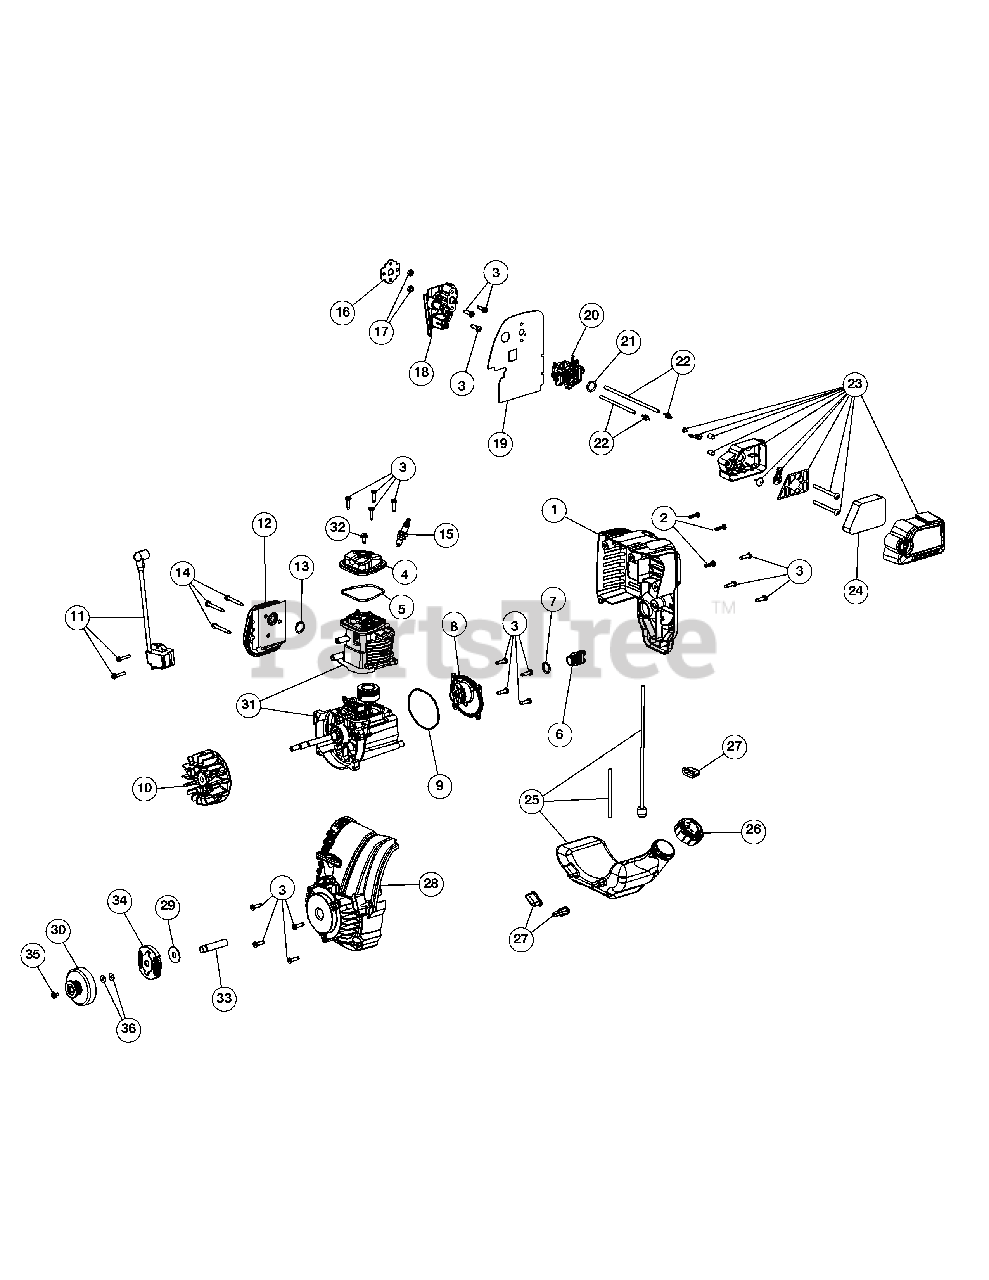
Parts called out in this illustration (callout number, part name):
1	Engine Cover Assembly (Incl. 2 & 3)
2	Cover Screw
3	Starter Screw
4	Rocker Cover
5	Rocker Cover O-Ring
6	Oil Plug (Incl. 7)
7	Oil Plug O-Ring
8	Crankcase Cover
9	Crankcase Cover O-ring
10	Flywheel Assembly
11	Module Assembly
12	Muffler Assembly (Incl. 13 & 14)
13	Muffler Gasket
14	Muffler Screw
15	Spark Plug
16	Insulator Gasket
19	Carburetor Gasket
20	Carburetor w/Primer
23	Air Cleaner Cover Assembly (Incl. 24)
24	Air Filter
25	Fuel Tank Assembly w/Fuel Lines (Incl. 26)
27	Fuel Tank Pads
28	Starter Housing Assembly (Incl. 3)
30	Clutch Drum w/Pulley
31	Shortblock Assembly
34	Clutch (Incl. 29)
36	Washer
